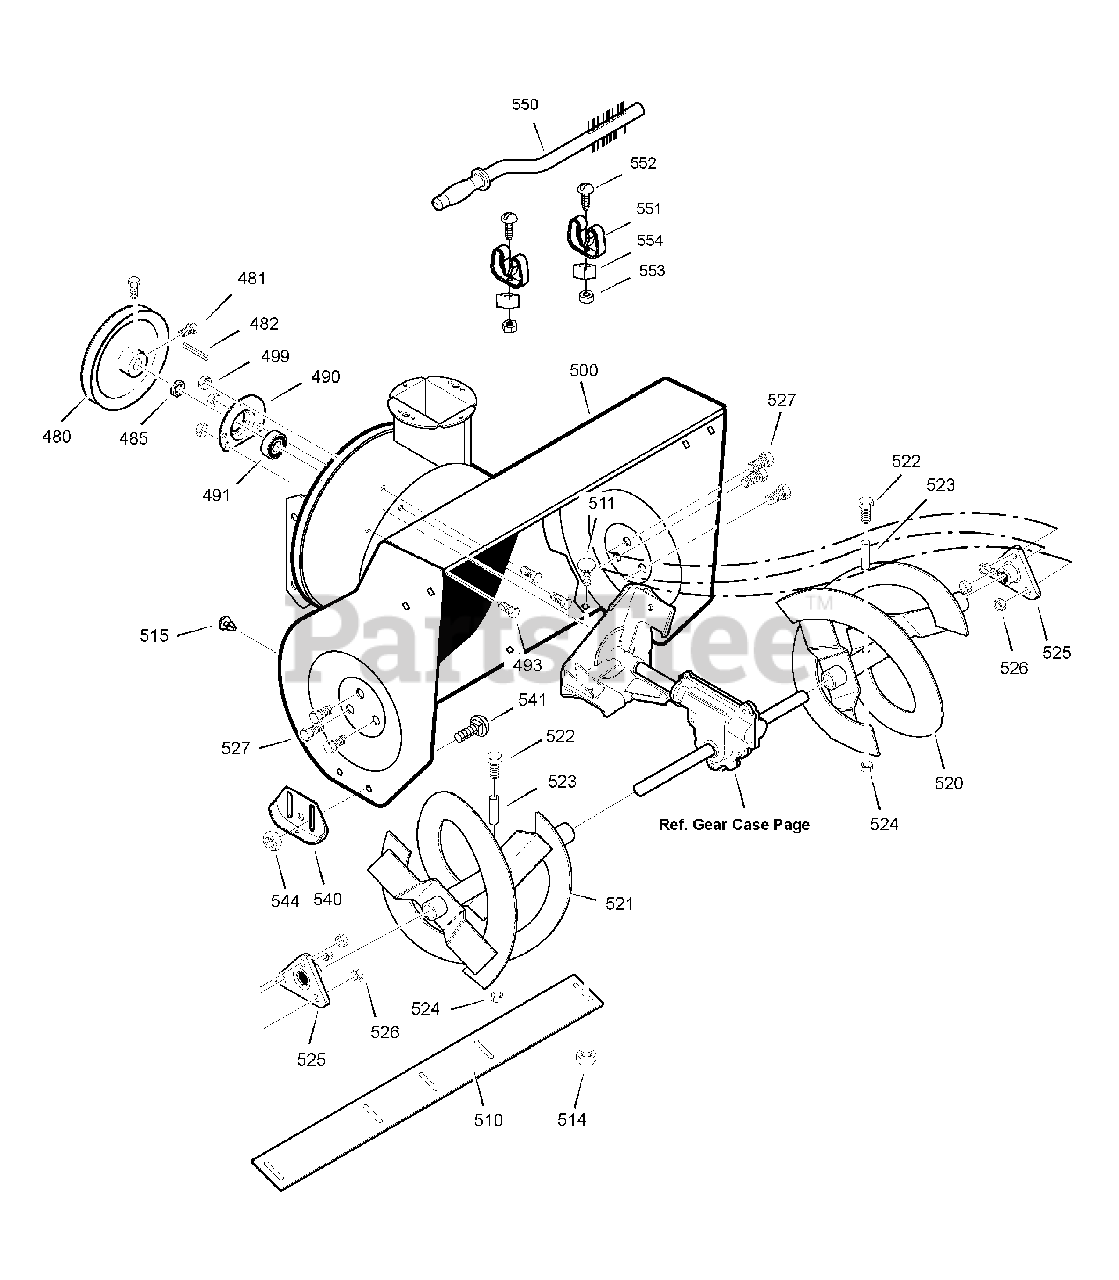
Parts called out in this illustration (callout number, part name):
480	PULLEY, 4L 6.12X .67
481	SCREW, 5/16-18 x 0.63
482	KEY, SQUARE 3/16 X 3/4
485	SPACER, FRICTION PULLEY
490	RETAINER, BALL BRNG
491	BEARING, BALL
493	BOLT, HEX 5/16-18X .50
499	NUT, 5/16-18 HEXWDFLLK
500	ASSY, HOUSING
510	BLADE, SCRAPER
511	BOLT, 5/16-18X.75
514	NUT, 5/16-18
515	PLUG
520	ASSY, LH AUGER
521	ASSY, RH AUGER
522	SCREW, 1/4-20X1.75
523	SPACER, SLEEVE
524	NUT, 1/4-20
525	BEARING, FLANGE
526	NUT, 5/16-18
527	SCREW, 5/16-18 x 0.75
540	SKID, HEIGHT ADJUST
541	BOLT, 5/16-18 X .75
544	NUT, 5/16-18
550	BRUSH, CLEANOUT
551	CLIP, RETAINER
552	SCREW
553	NUT
554	BLOCK
